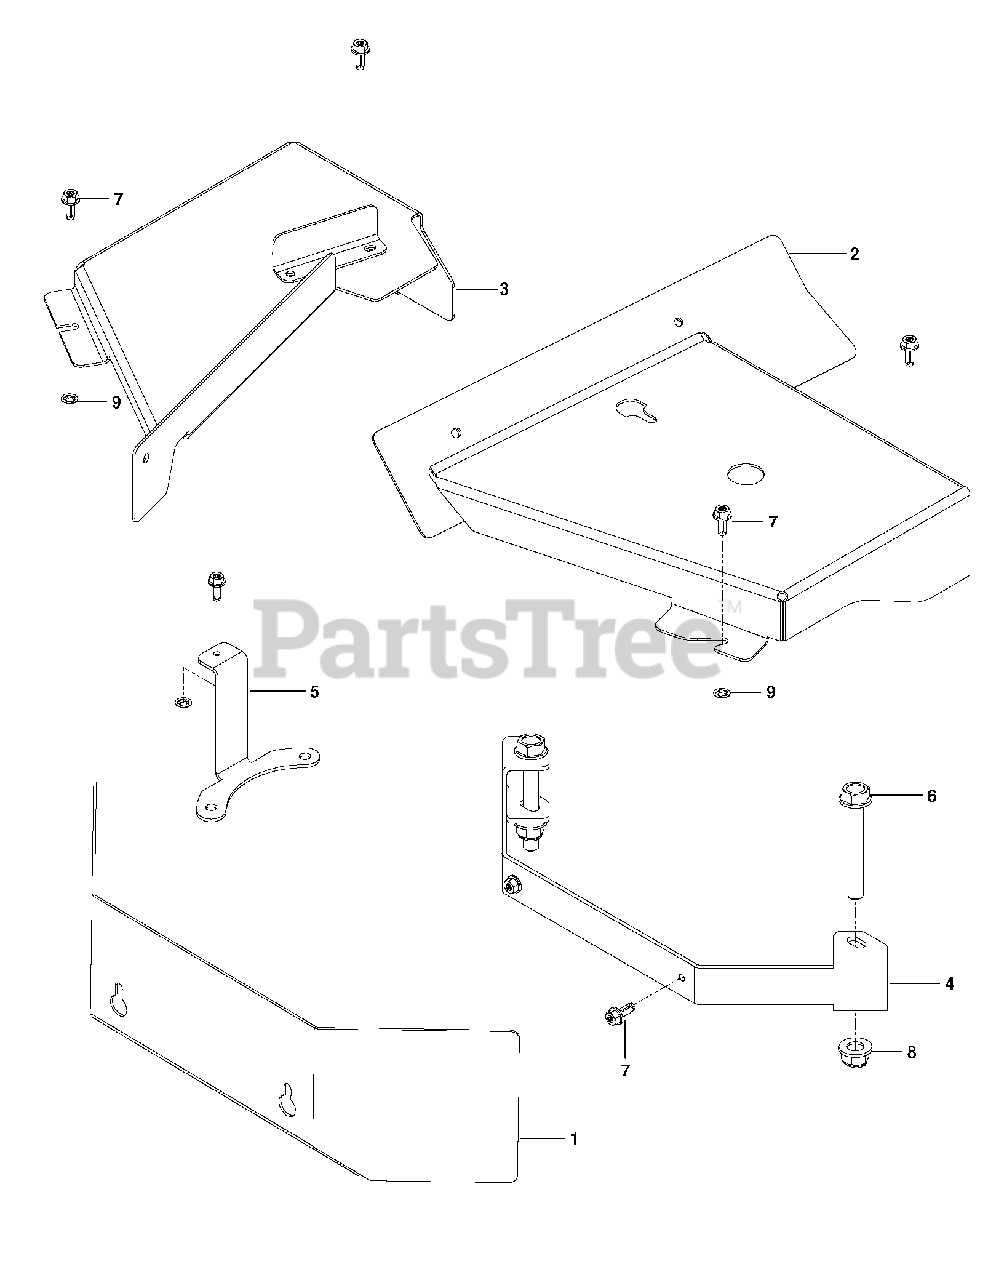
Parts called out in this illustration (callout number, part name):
6	HHFS 5/16-18 X 2.25 GD 5
7	SCREW- 1/4-20 X 5/8
8	5/16-18 NYLOC FLANGE NUT
9	PALNUT 1/4
